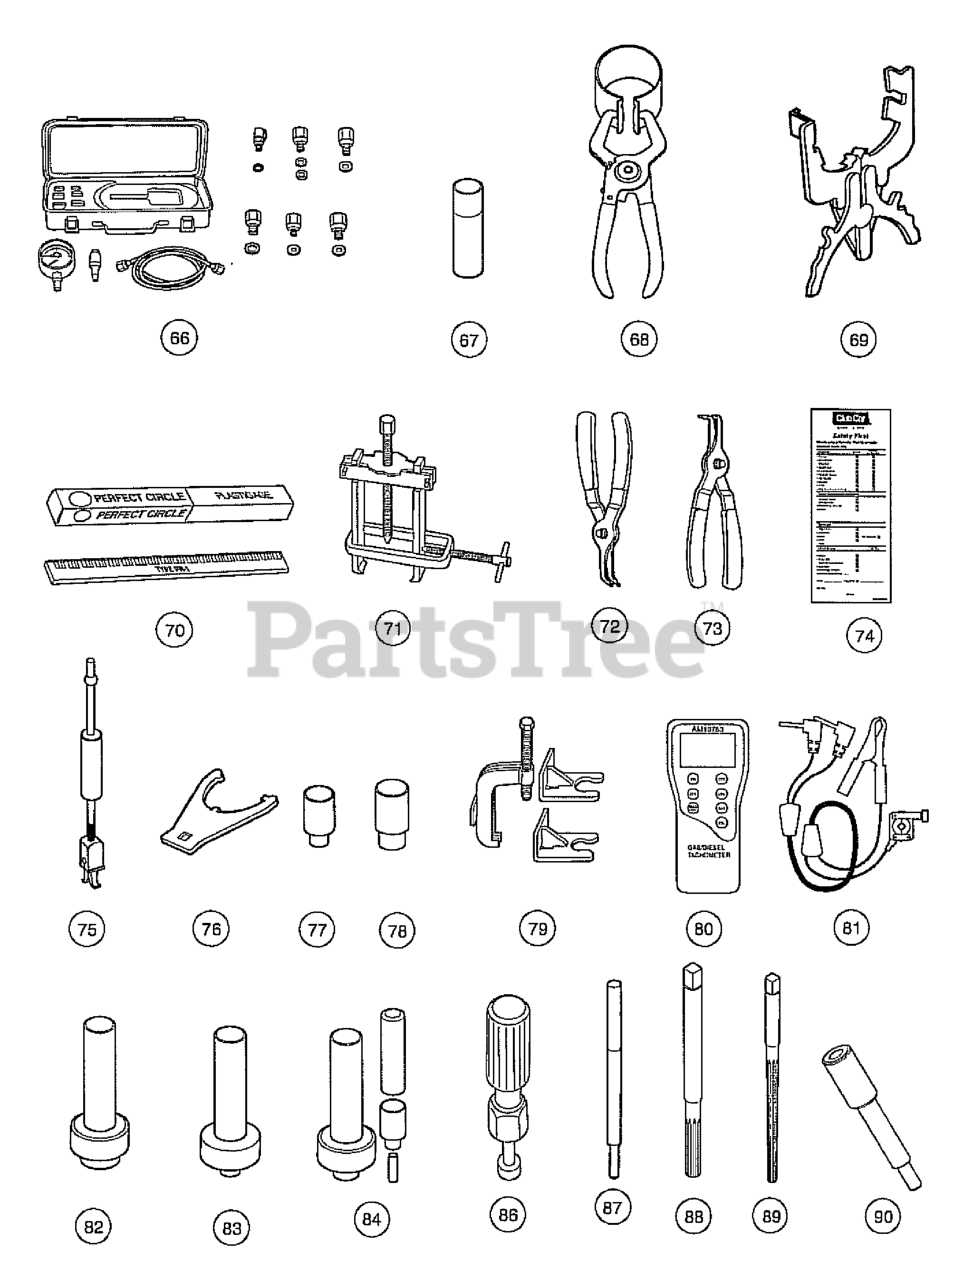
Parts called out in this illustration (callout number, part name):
66	Oil Pressure Tester
67	TOUCH UP PAINT BEIGE
67	TOUCH UP PAINT BLACK
67	TOUCH UP PAINT BURGANDY
67	TOUCH UP PAINT CLASSIC BLUE
67	TOUCH UP PAINT DARK GRAY
67	TOUCH UP PAINT DARK GREEN
67	TOUCH UP PAINT GRAY
67	TOUCH UP PAINT RED
67	TOUCH UP PAINT ROYAL BLUE
67	TOUCH UP PAINT WHITE
68	KIT, PISTON RING COMPRESSOR
69	PISTON RING PLIER
70	Plastigage
71	SPECIAL-USE PULLER SET
72	EXTERNAL SNAP RING PLIERS
73	INTERNAL SNAP RING PLIER 9O
74	SAFETY FIRST CARD
75	SEAL PULLER
76	WRENCH, SPANNER
77	Steering Column Bearing Press Tool
78	TOOL-STEERING RETAINING RING
79	PULLER, STEERING WHEEL
80	TACHOMETER GAS/DIESEL
81	Tachometer Diesel Probe
82	TRANS-AXLE, AXLE SEAL TOOL
83	Transaxle Pinion Seal Tool
84	Transmission Tool Kit
86	VALVE CLEAR ADJ SCREW HOLDER
87	DRIVER, VALVE GUIDE, 6.6. MM
88	VALVE GUIDE REAMER
89	REAMER-VALVE GUIDE
90	Valve Guide Replacement Tool
